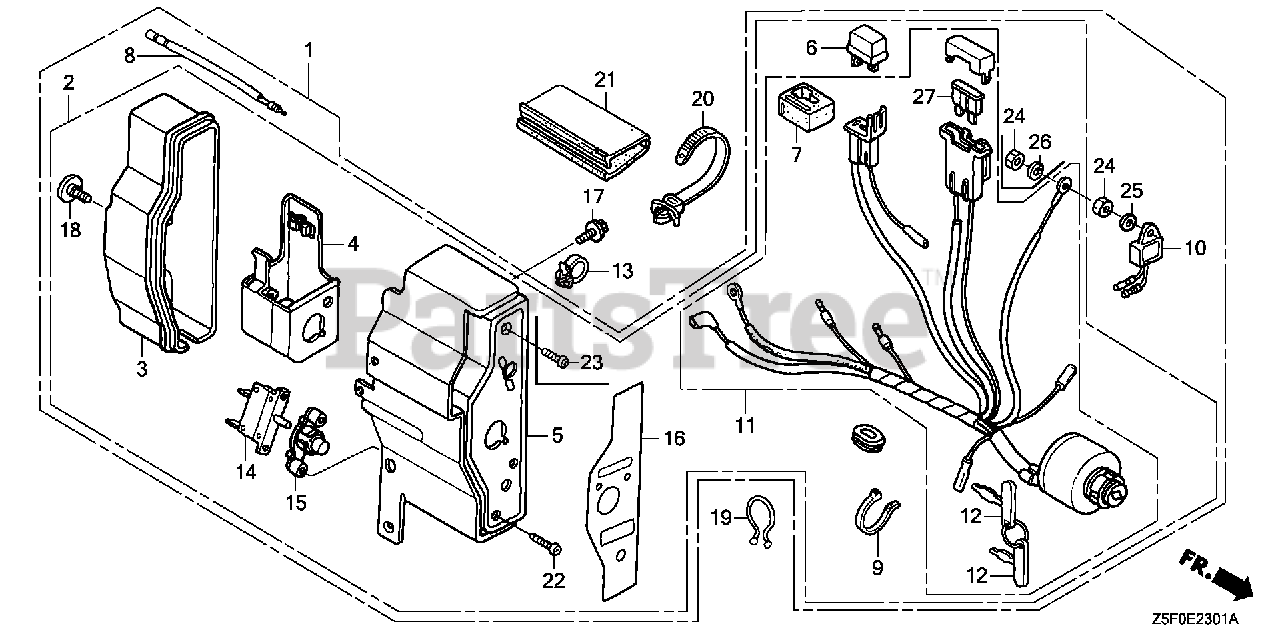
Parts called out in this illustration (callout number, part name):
1	BOX ASSY., CONTROL *R280* (EXP-ALERT) (POWER RED)
3	CASE, CONTROL
4	BRACKET, CASE MOUNTING
5	PANEL, CONTROL *R280* (POWER RED)
6	RECTIFIER ASSY., SILICON (SHINDENGEN)
7	SUSPENSION, CONNECTOR
8	SUB-WIRE HARNESS
10	ALERT UNIT, OIL
11	SWITCH ASSY., COMBINATION
12	KEY (HONDALOCK)
13	HOLDER, STOP SWITCH WIRE
14	PROTECTOR, CIRCUIT (1.0A)
15	LENS ASSY., PROTECTOR
16	MARK, CONTROL BOX (EXTERNAL)
17	BOLT, FLANGE (6X12) (CT200)
18	SCREW, SPECIAL (6X12)
19	CLIP, PURSE LOCK
20	STRAP, CABLE (118MM) (BLACK)
21	TUBE, FASTENER (30MM)
22	SCREW, PAN (3X12)
23	SCREW, PAN (4X12)
24	NUT, HEX. (4MM) (SOURCE: VINTAGE PARTS INC.)
25	WASHER, PLAIN (4MM)
26	WASHER, SPRING (4MM)
27	FUSE, BLADE (5A)
